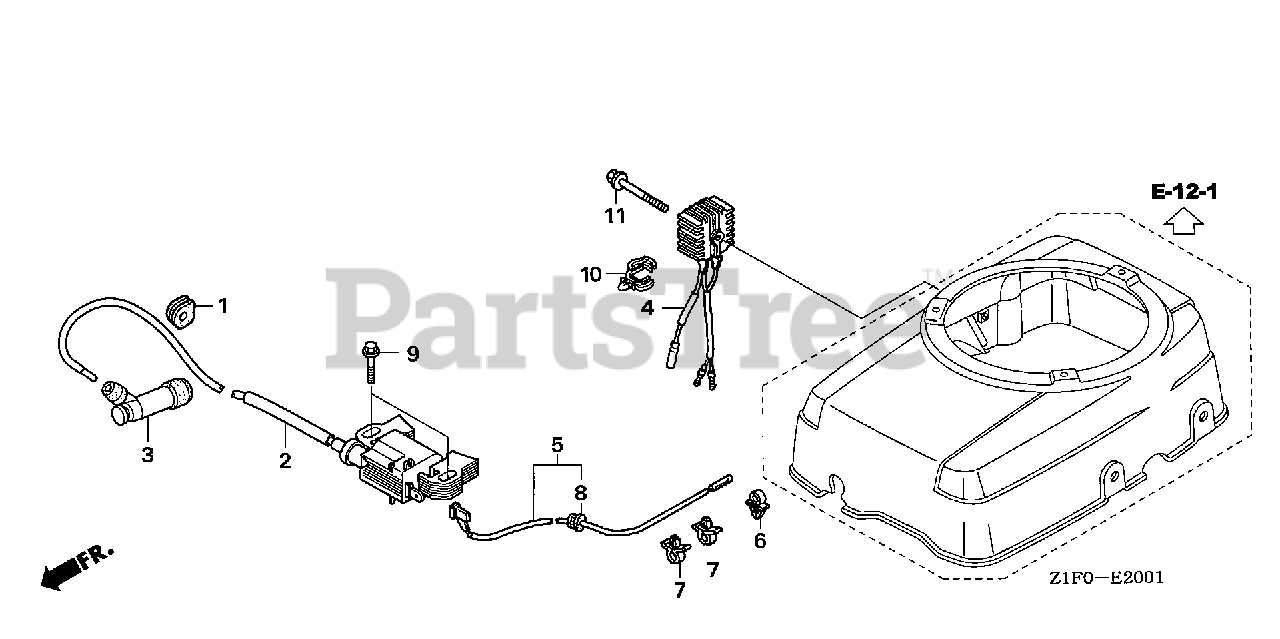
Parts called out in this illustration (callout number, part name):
1	GROMMET, WIRE
2	COIL ASSY., IGNITION
3	CAP ASSY., NOISE SUPPRESSOR
4	RECTIFIER ASSY., SILICON
5	WIRE, STOP SWITCH
6	HOLDER, STOP SWITCH WIRE Use up to Engine SN 2056819.
6	HOLDER, WIRE (FASTEX)
7	CLIP, BRAKE PIPE (A) (FOR NEUTRAL SWITCH)
8	GROMMET, WIRE
9	BOLT, FLANGE (6X28) (CT200) Use up to Engine SN 1530314.
10	CLIP, WIRE HARNESS
11	BOLT, FLANGE (6X40)
